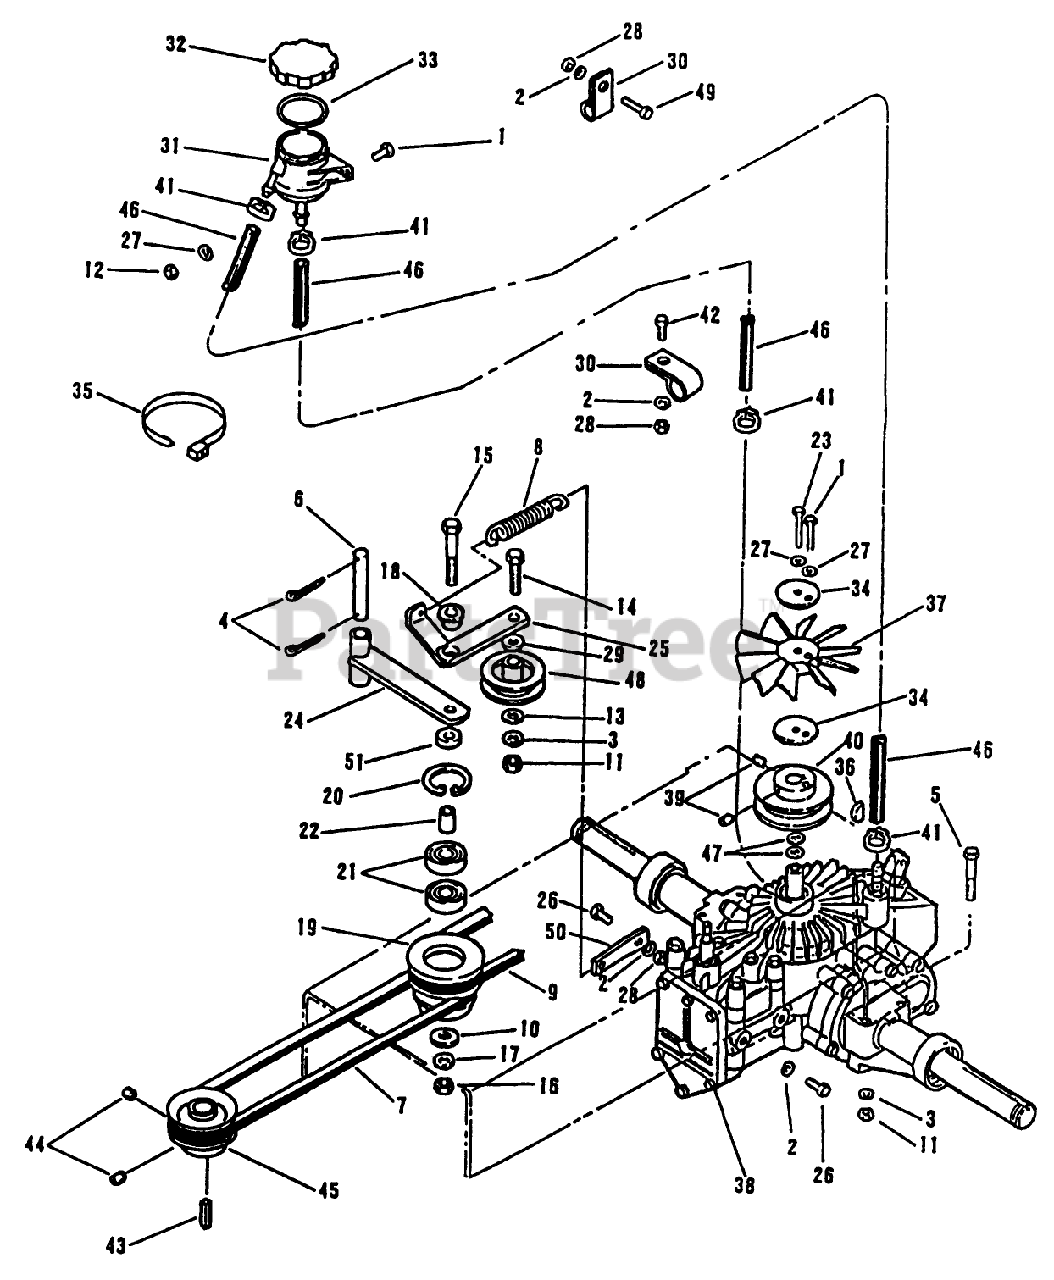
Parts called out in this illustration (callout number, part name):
19	IDLER ASSEMBLY
24	IDLER ARM WELDMT *B
26	SCREW - HEX
33	GASKET,COVER
34	FRAME MTG WASHER LB
41	CLAMP, SNAP
44	SET SCREW
46	HOSE-HYDRAULIC
